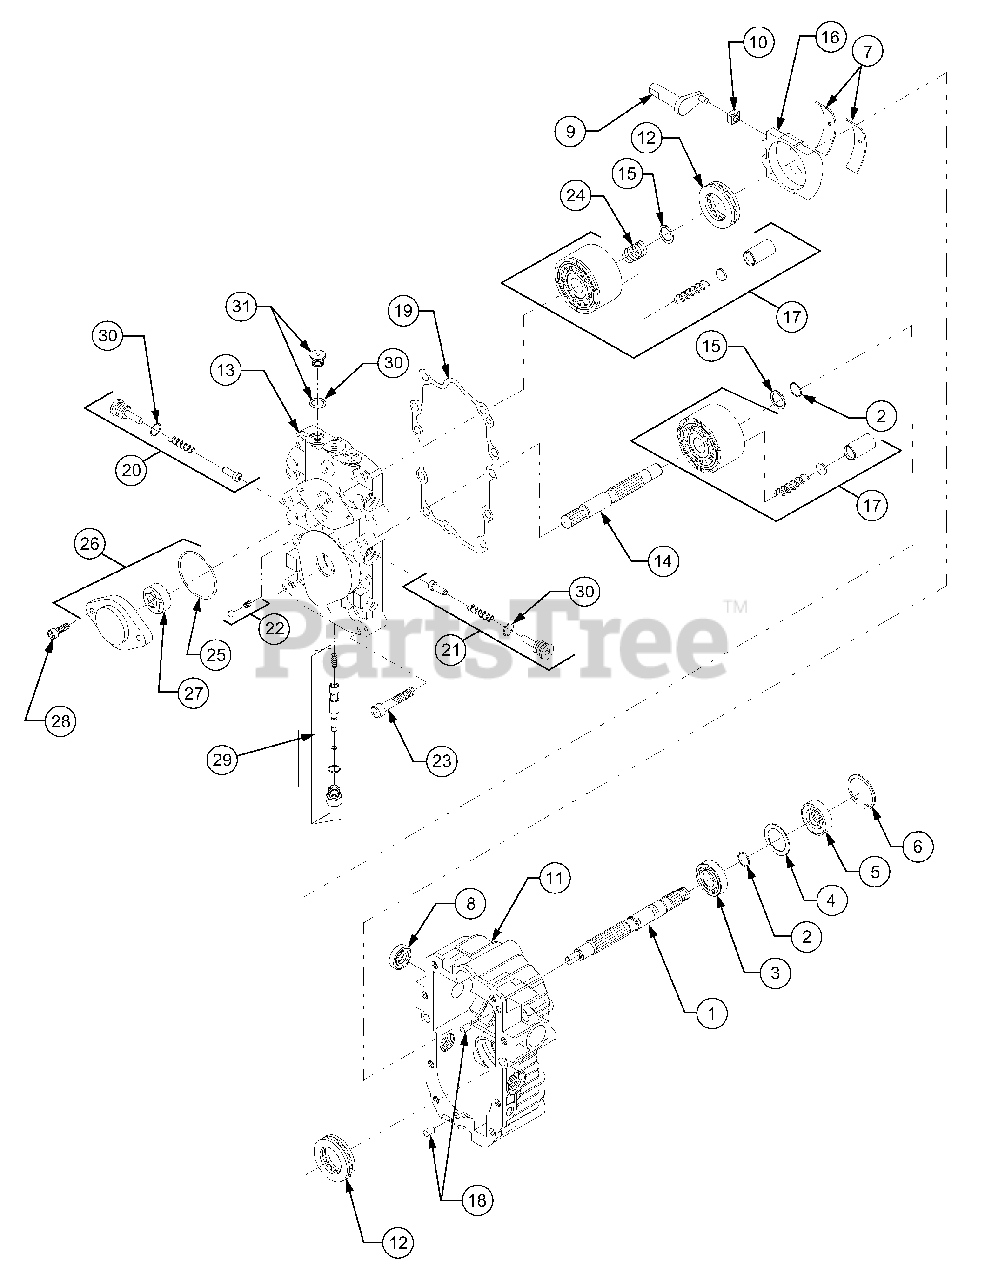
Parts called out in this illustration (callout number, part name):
1	Shaft, Pump (Splined)
2	Ring, Retaining
3	Bearing, Ball
6	Ring, Retaining
7	Bearing, Cradle
9	Arm, Trunnion
10	Guide, Slot
11	Housing Kit
12	Bearing Assembly, Thrust Ball
13	Center Section Kit
14	Shaft, Motor
15	Washer, Block Thrust
16	Swash Plate
17	Block Assembly
19	Gasket, Center Section
20	Kit, Check Valve
21	Kit, Orificed Check Valve
22	Kit, Charge Relief Valve
23	Screw, Socket Hd
24	Spring, Block
26	Kit, Charge Pump
27	Gerotor Assy
28	Screw, Socket Hd
29	Bypass Valve Kit
